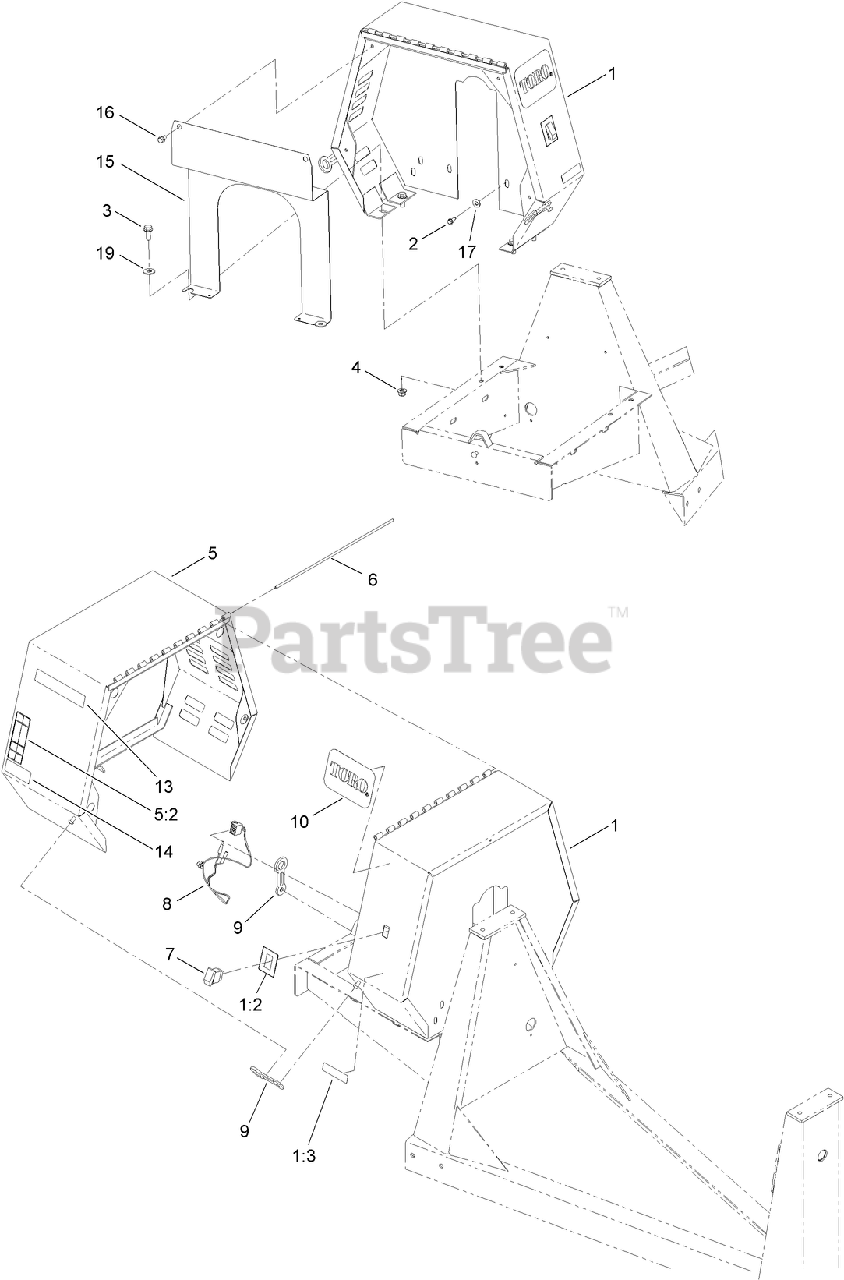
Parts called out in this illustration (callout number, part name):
1	STATIONARY COWL ASM
1:2	DECAL-STOP, ENGINE
1:3	DECAL-ARRESTER, SPARK
2	SCREW-HWHTF
3	SCREW-HHF
4	NUT-LOCK
5	MOVABLE COWL ASM
5:2	DECAL-WARNING
7	SWITCH
8	HARNESS-WIRE, MIXER
9	LATCH-RUBBER
10	DECAL
15	PLATE-ENGINE
16	SCREW-HWH
17	WASHER-FLAT
19	WASHER-FLAT
